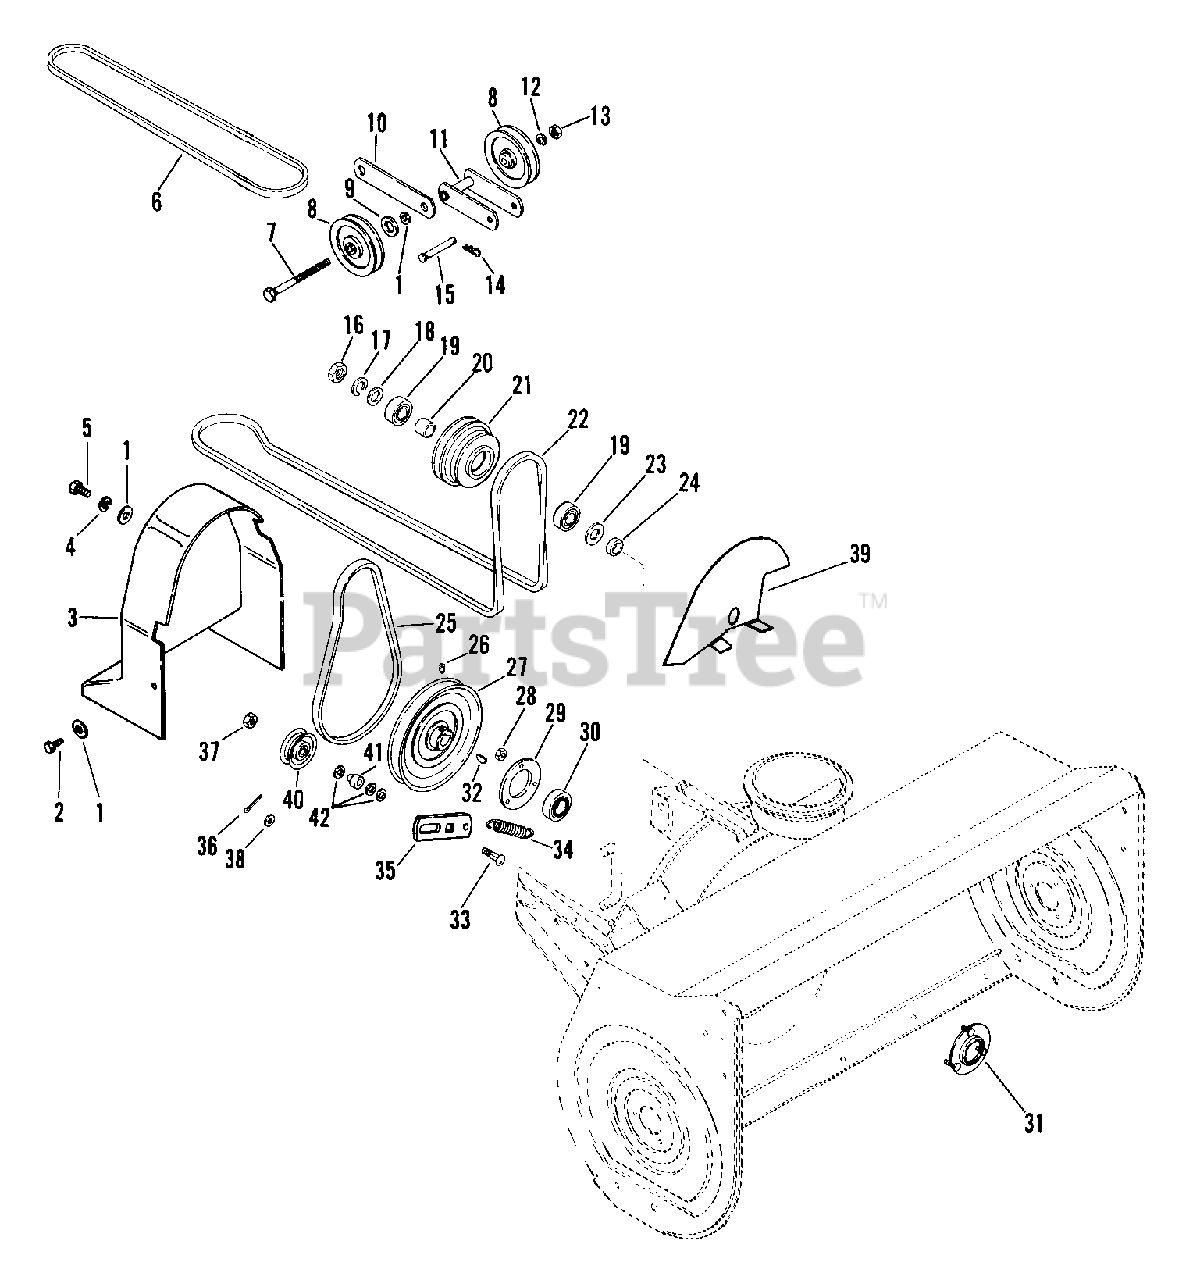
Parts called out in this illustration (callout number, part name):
1	WSHR-FL-STL .382X.812X.062
2	SCR-TAP .312-18X.50 HWH PL TR
3	BELT GUARD
4	WSHR-LK .312X.097 PL HVY
5	BLT-HEX .31-18X.75 PL GR5
6	V-BELT, 4L-RAW EDGE
7	BLT-HEX .38-16X5.00 PL GR2
8	IDLER-V 4.00 X .38 NWHAMSHR
9	WSHR-FL-STL .755X1.375X.062 PL
10	STRAP
11	IDLER BRACKET
12	WSHR-LK .375X.115 HVY PL
13	NUT-HEX .375-16
14	PIN-HAIR INT .08X.38X1.42 YWZC
15	CLEVIS PIN 3/8X3.0 YWZC
16	NUT-JAM .75-10 PL
17	WSHR-LK-INT .750X.050 MED
18	WSHR-FL-STL .781X1.250X.059 PL
19	BRG-BALL .750X1.781X.61
20	SPACER 1.00 X .770/.760 X .813
22	V-BELT, HA-WRAPPED
23	WSHR-FL-STL .781X1.500X.188
24	SPACER .76/.77 X 1.00 X .30
26	SCR-SET .32-18X.50 SKHCUP OH
27	PLY-V 7.50 X .75 W/KEY SALEM
28	NUT-LK-CTR .250-20 PL
29	BEARING FLANGE
30	BRG-BALL .984X2.047X.59
31	BEARING FLANGE
32	KEY-WDRF .188X.875X.375 SAE11
33	BLT-RDHDSQNK .38-16X1.50 PL
34	SG-TENS .090X.75X3.50 WLD 34
35	IDLER ARM
36	PIN-COTR .12X.75 PL
37	NUT-LK-CTR .375-16 GR A PL
38	WSHR-FL-STL .382X.812X.023 PL
39	SHIELD
40	IDLER
41	SPACER -FLANGED .390X.500X.781
42	WSHR-FL-STL .505X.880X.072 PL
